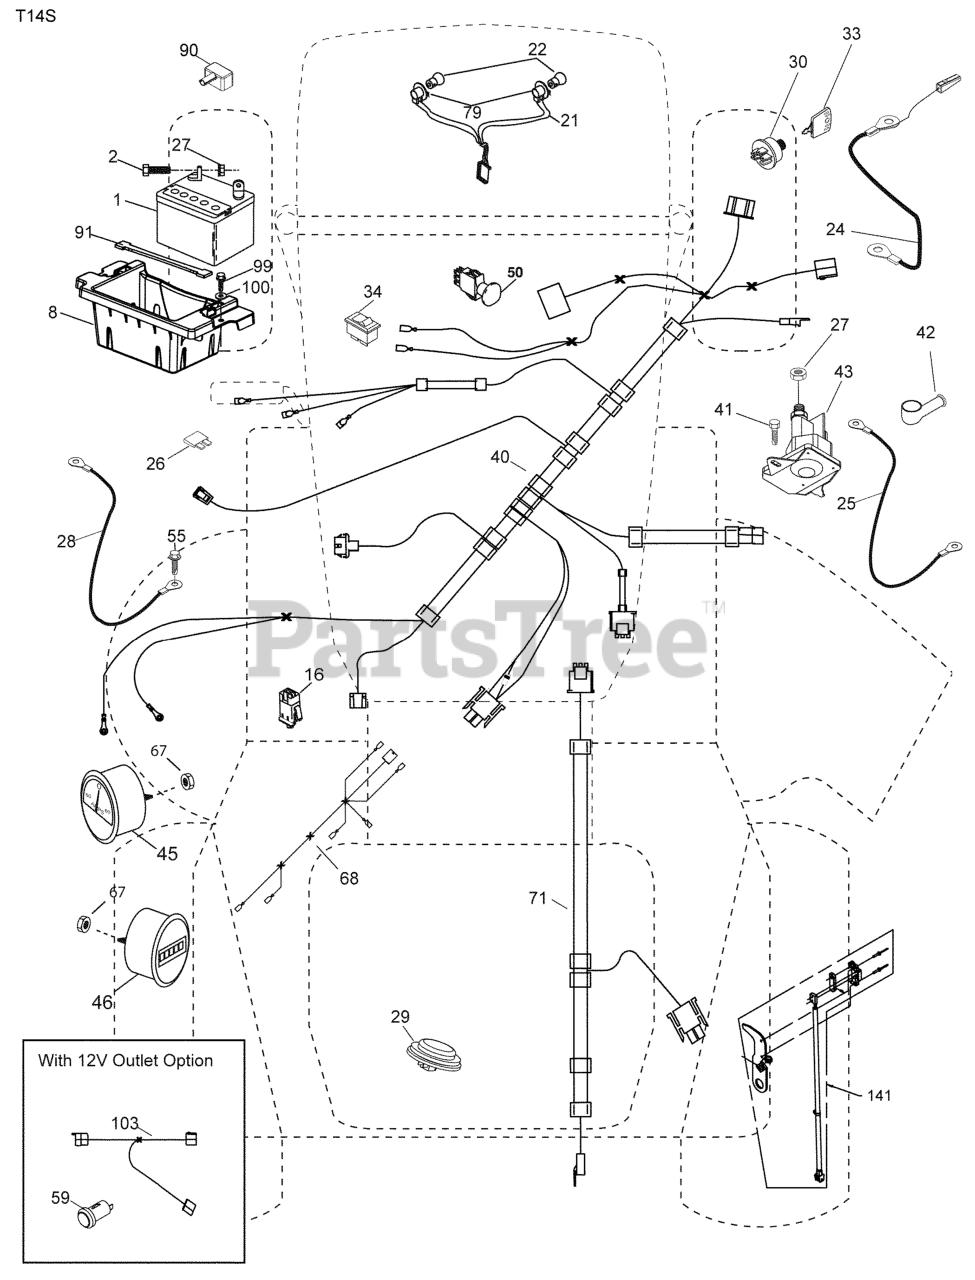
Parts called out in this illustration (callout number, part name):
1	Battery
2	BOLT.HEX.1/4.X.3/4.DICHROMATE
8	BOX.BATTERY.MOUNT.FRONT.LT
16	SWITCH INTERLOOK PUSH-IN
21	HARNESS ASSY LIGHT
22	Bulb, Light
24	CABLE.BATT.POS.WIRE.TG.DA SOL
25	CABLE.STARTER.6G.BL/RED.17.5
26	FUSE 20AMP
27	NUT
28	CABLE GROUND 6 GA 21" 90T BLK
29	SWITCH.SEAT.DELTA.OPC.
30	SWITCH.IGN.DELTA.W.LGH.ROS
33	KEY.CHAIN.BLISTER.PACK.GEN.INT
40	HARNESS IGN. DASH
41	SCREW
42	TERMINAL COVER
43	SOLENOID.W/BRASS.PLUNGER
45	AMMETER.STUDMOUNT.ROUND.SNAPIN
46	HOURMETER.STUDMOUNT.LS
50	RP.PTO.SWITCH.8 TERMINAL.BLACK
55	SCREW 5/16"
59	OUTLET.12-VOLT
67	NUT.10-32.EXTLOCK
68	HARNESS.JUMPER.GAUGES
71	HARNESS-CHASSIS SUB
79	BULB HOLDER ASM.
90	COVER.TERMINAL.BATTERY
91	STRAP.BATTERY.MOUNT.FRONT(2 2)
99	SCREW HEXWSHR 1/4-20X3/4
100	WASHER
103	HARNESS.PIGTAIL.12V.OUTLET.
141	KIT.G700/G730.ROS 71750
